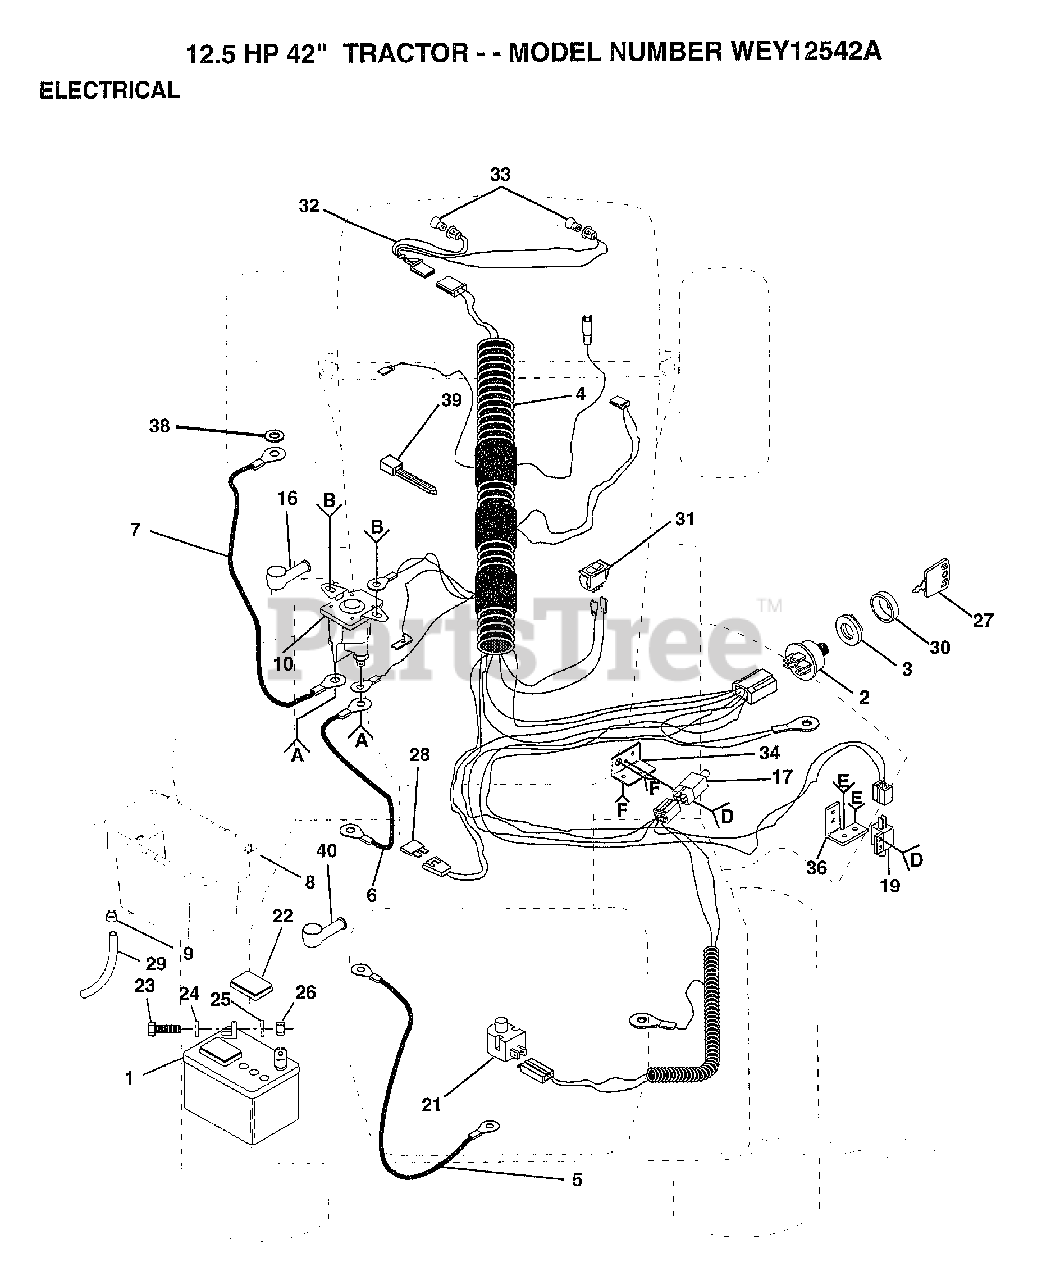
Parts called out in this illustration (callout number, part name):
3	NUT IGNITION
4	HARNESS.IGN.B&S
5	CABLE T
7	CABLE-BATTERY T
8	BTRY CASE W/O LID
9	HOSE CLAMP T
12	NUT
13	BOLT
15	NUT
17	SWITCH INTERLOCKT
19	SWITCH-INTER. GT
20	SCREW
21	SWITCH SEAT
22	"CAP,BATTERY "
23	BOLT LT
24	WASHER
25	LOCKWASHER
27	KEY
28	FUSE HYT
29	TUBE T
31	SWITCH LT
34	SWITCH BRACKET
35	SCREW
36	BRACKET LT
37	SCREW
38	LOCKWASHER
39	WIRE TIE
